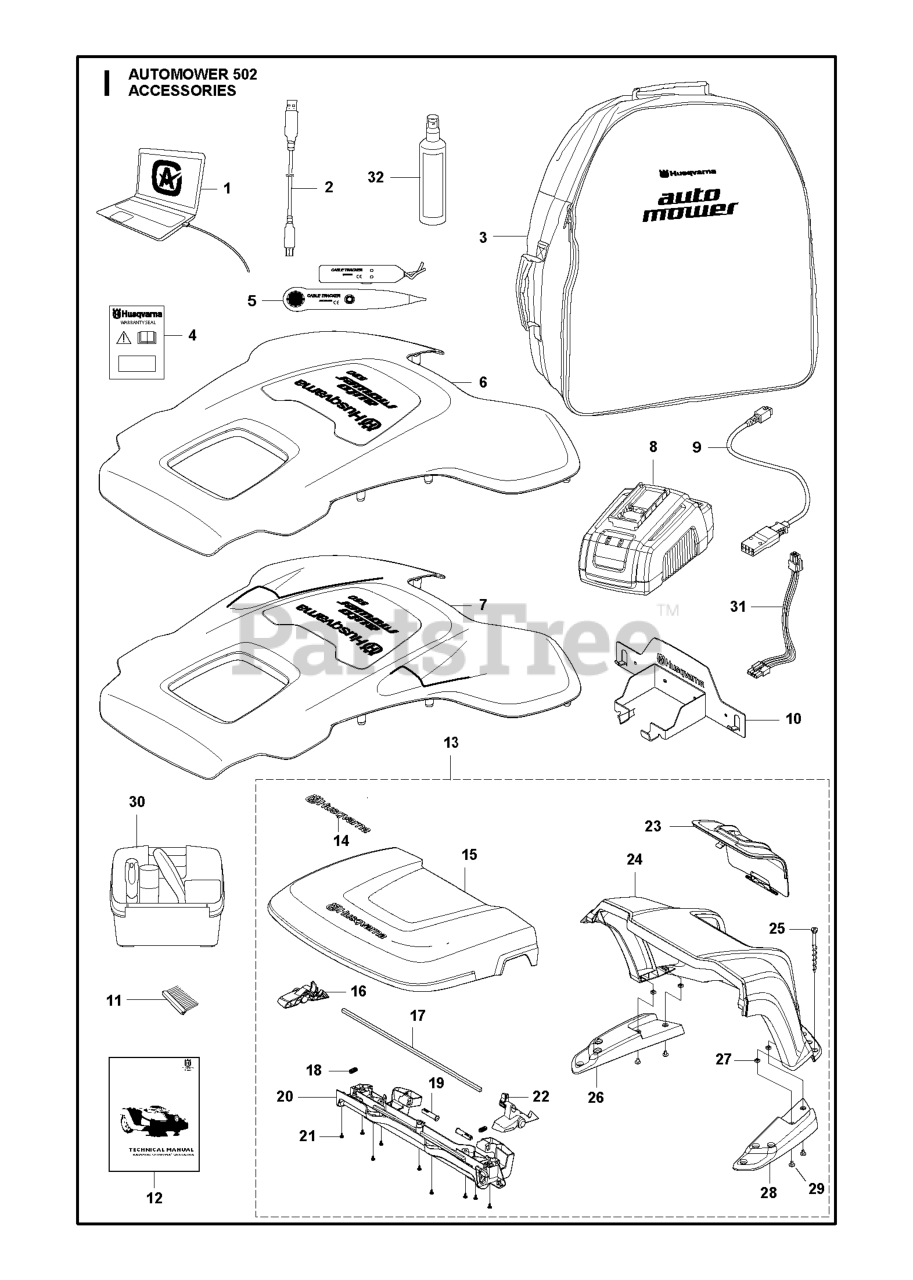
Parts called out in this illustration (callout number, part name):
2	CABLE WHITE ALT GREY
3	BAG
4	LABEL WARRANTY SEAL DEALER
5	TEST EQUIPMENT
8	CHARGER BATTERY TEST
9	CABLE ASSY QUICK CHARGER
10	MISC. BLISTER WALL HANGER
11	WHEEL BRUSH REFILL KIT
13	430/450 HOUSE KIT
14	DECAL.HUSQVARNA.210MM
15	KIT LID - AUTOMOWER HOUSE
16	HANDLE RELEASE LEFT
17	ROD
18	SPRING SPRING CAP
19	HINGE PIN
20	BEAM
21	SCREW 14MM
22	HANDLE RELEASE RIGHT
23	HATCH
24	COVER BASE P2 HOUSE
25	SCREW KIT CS
26	SUPPORT BASE LEFT
27	NUT
28	SUPPORT BASE RIGHT
29	SCREW IHPANM M6X25 4.6 ZP-BC
30	CLEANING AND MAITENANCE KIT AM
31	WIRING ASSY BATTERY CABLE
32	AUTOMOWER ACCY
